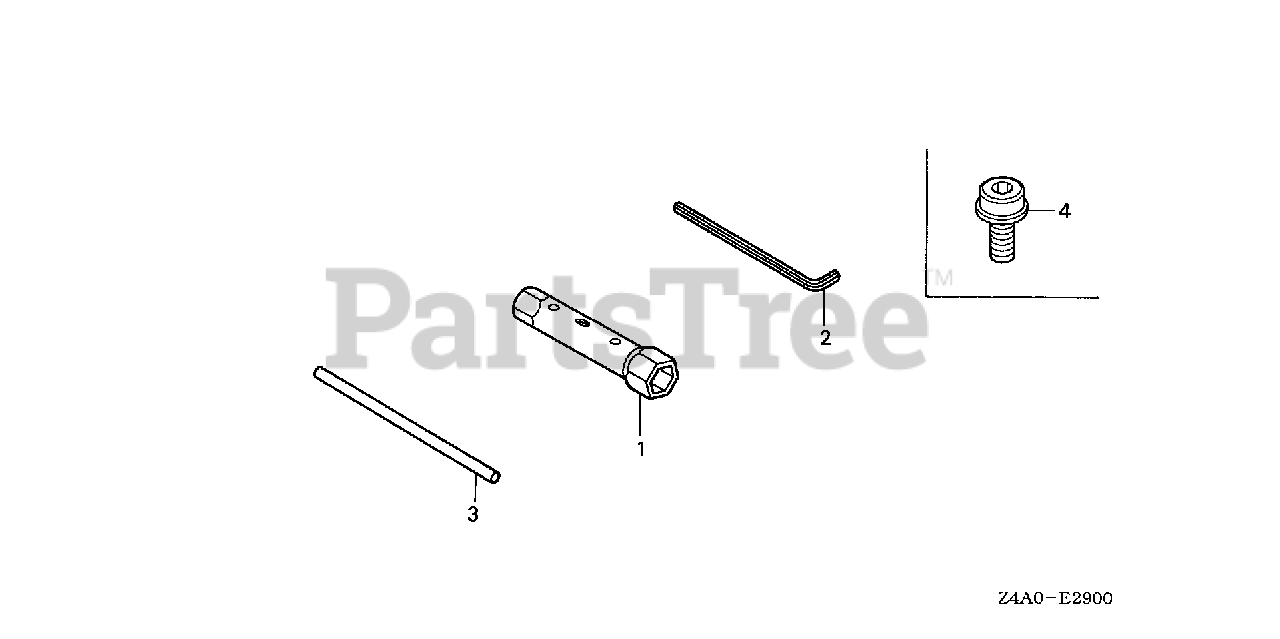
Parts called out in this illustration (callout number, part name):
1	WRENCH, SPARK PLUG
2	WRENCH, HEX. (4MM)
3	BAR A, HANDLE
4	BOLT, SOCKET (5X9)
